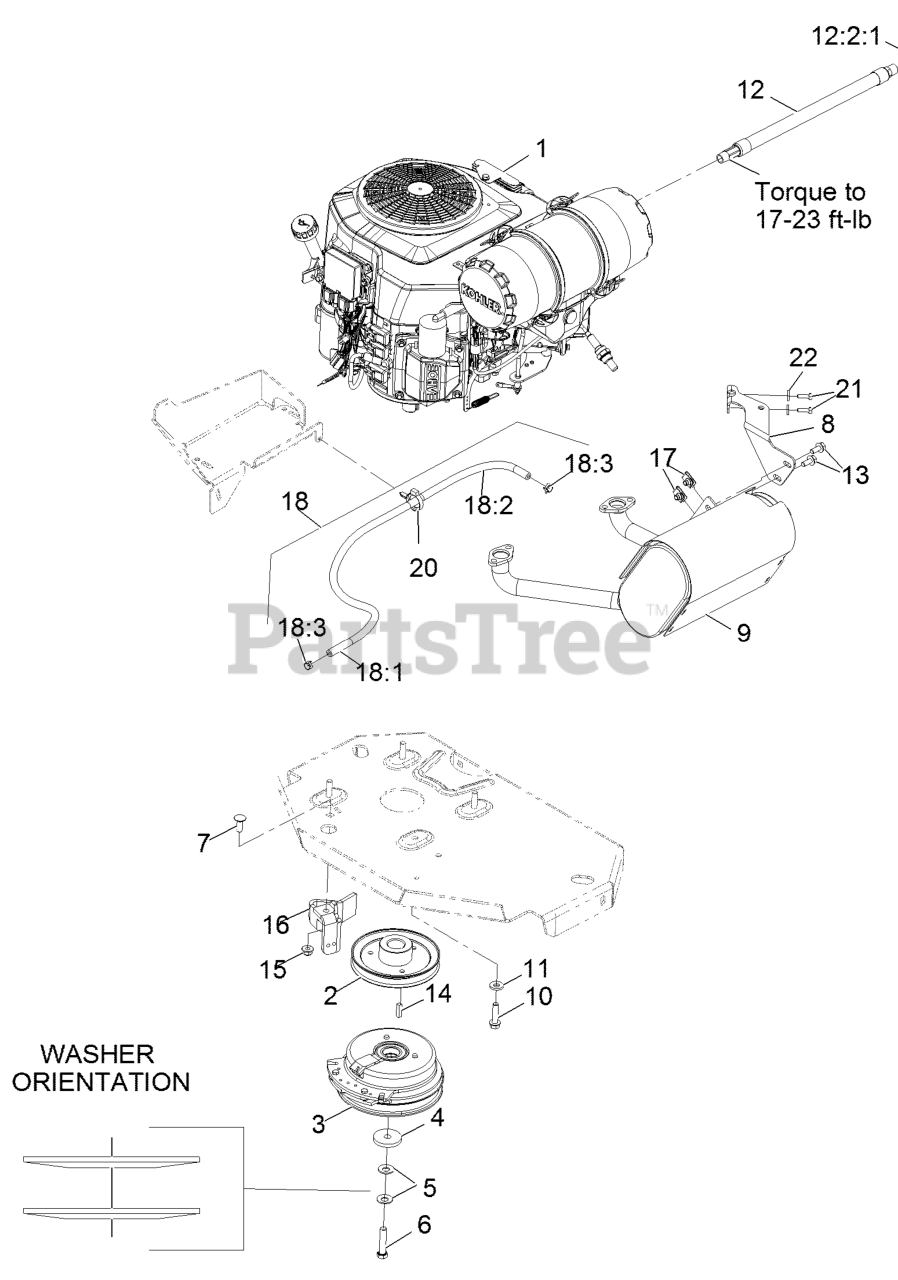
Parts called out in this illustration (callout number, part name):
2	SHEAVE
3	CLUTCH KIT
4	WASHER-CLUTCH
5	WASHER-SPRING
6	SCREW-HH 7/16-20 X 1 1/2 W/LOCTITE
7	SCREW-CARR
8	MUFFLER BRACKET KIT
10	SCREW-HWH
11	WASHER-BELLEVILLE
12	OIL DRAIN HOSE ASM
12:2	PLUG-HH
12:2:1	O-RING
13	SCREW-HHF
15	NUT-HF, NI
16	CLUTCH-ANCHOR
18	FUEL LINE ASM
18:1	HOSE-FUEL
18:2	SLEEVE-THERMAL
18:3	CLAMP-HOSE
20	CLAMP-HOSE
21	SCREW-HH M6-1 X 20Mm W/Patch
22	WASHER-SPRING
